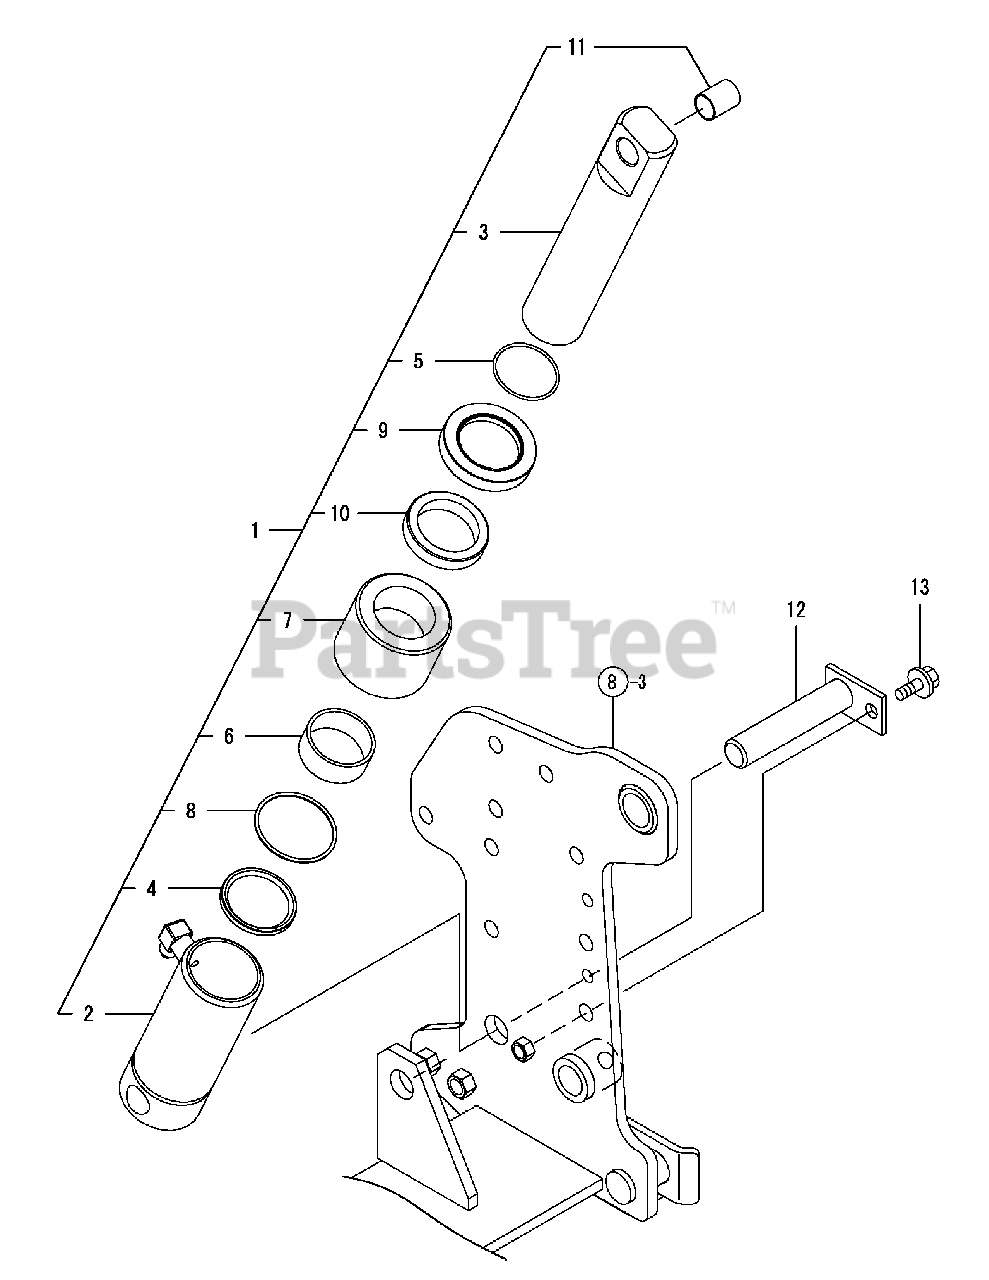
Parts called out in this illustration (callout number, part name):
1	CYLINDER ASSY, HYD.
12	PIN CMP CYLINDER
13	BOLT M10X 25 PLATED
